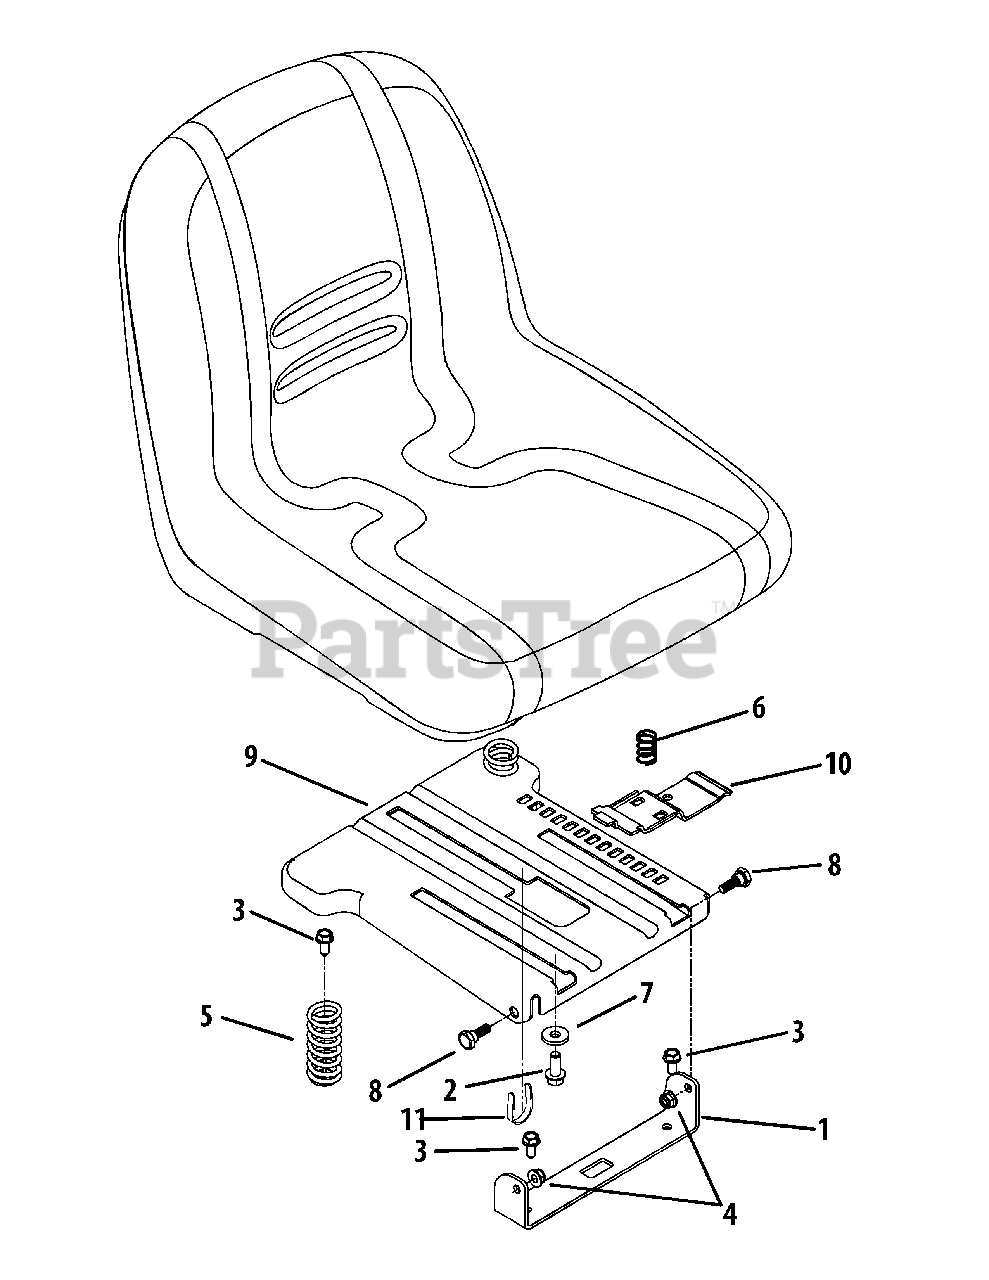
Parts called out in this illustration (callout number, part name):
2	Hex Flange Bolt 3/8-16 x .875
3	Hex Washer Screw 5/16-18 x .75
4	Flange Locknut 5/16-18 Gr. F, Nylon
5	Compression Spring
6	Compression Spring
7	Flat Washer .385 x 1.0 x .135
8	Shoulder Screw
10	Seat Adjustment Lever
